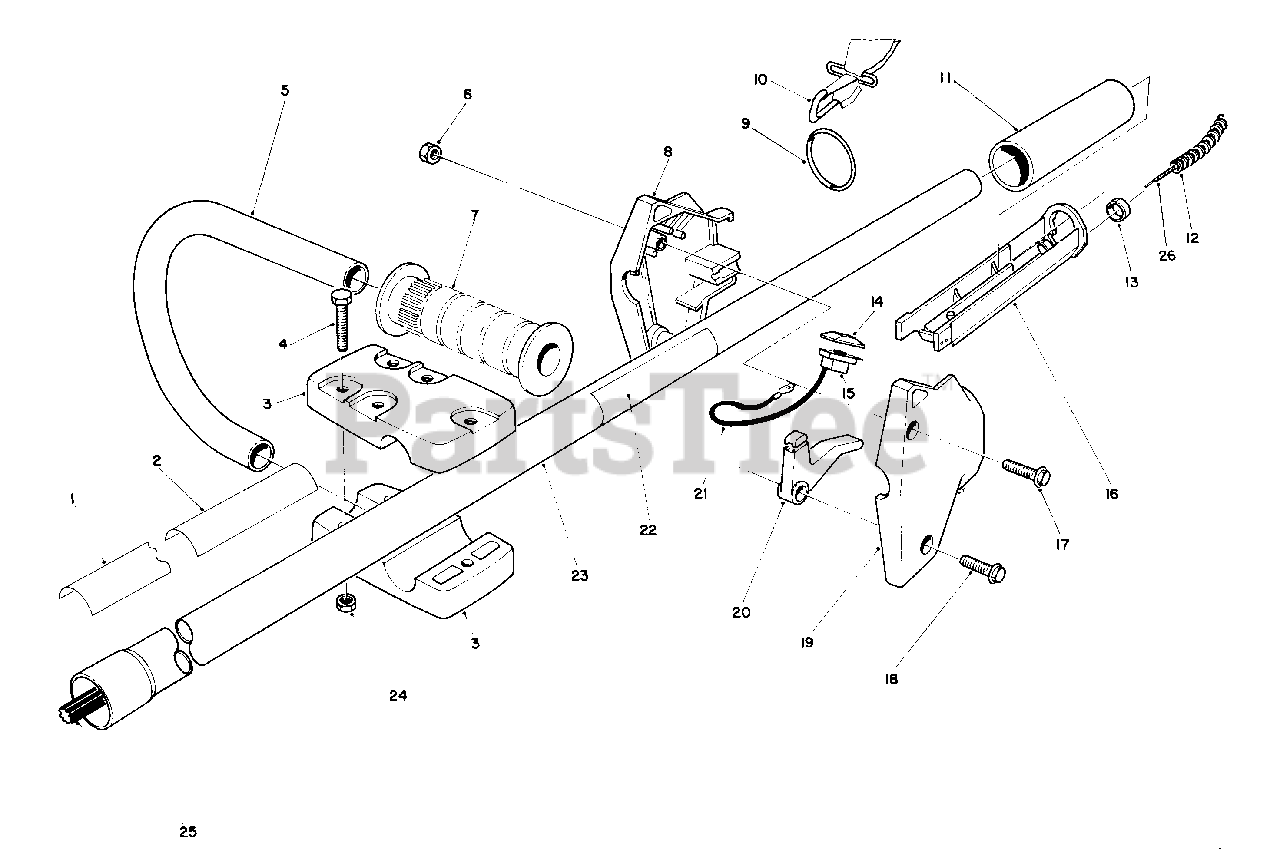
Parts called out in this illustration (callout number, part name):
1	Decal-TC 3510
2	Decal-Danger
3	Clamp-Secondary
4	Screw-Hex. Hd. Machine
5	Handle-Secondary
6	Nut-Lock
7	Grip-Handle
8	Housing R.H.
9	Ring-Harness
10	Harness-Shoulder
11	Grip-Drive Housing
12	Cover-Cable
14	Cap-Switch
17	Screw-Hex. Hd.
18	Screw-Hex. Hd.
19	Housing L.H.
20	Lever-Throttle
22	Decal-Instruction
23	Tube Assembly
24	Nut-Lock
25	Shaft-Spline, Drive
26	Cable-Throttle
